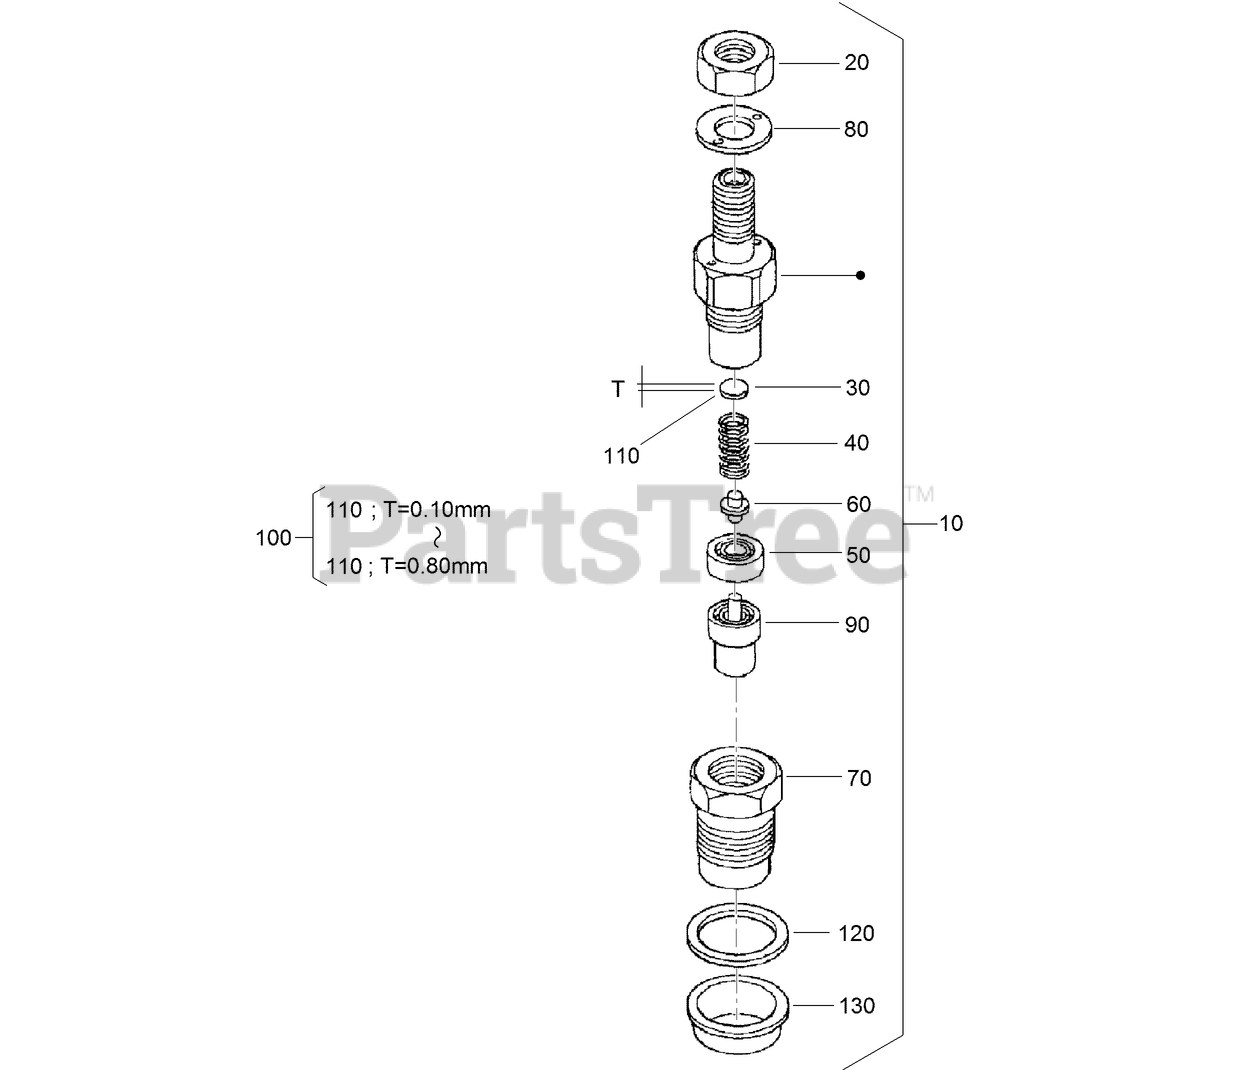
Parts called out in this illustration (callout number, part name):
10	NOZZLE HOLDER KIT
30	WASHER-ADJUSTING
40	SPRING-NOZZLE
50	SPACER-DISTANCE
60	ROD-PUSH
70	NUT-NOZZLE
80	WASHER-PLAIN
90	PIECE-NOZZLE
100	ADJUSTING WASHER ASM
110	WASHER-ADJUST (0.10MM)
110	WASHER-ADJUST (0.20MM)
110	WASHER-ADJUST (0.30MM)
110	WASHER-ADJUST (0.40MM)
110	WASHER-ADJUST (0.50MM)
110	WASHER-ADJUST (0.52MM)
110	WASHER-ADJUST (0.54MM)
110	WASHER-ADJUST (0.56MM)
110	WASHER-ADJUST (0.58MM)
110	WASHER-ADJUST (0.80MM)
120	GASKET
130	SEAL-HEAT
